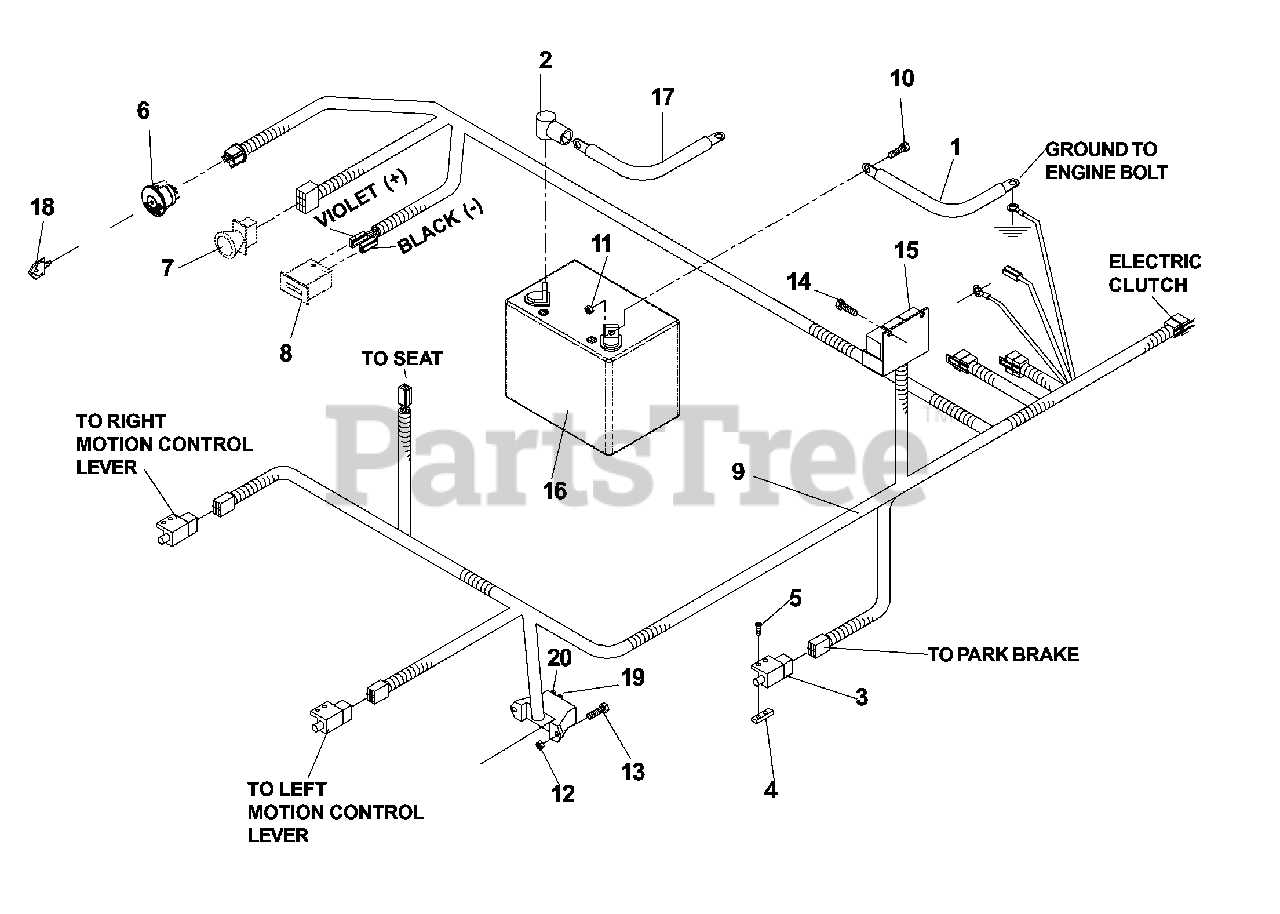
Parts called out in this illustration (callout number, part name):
1	CABLE-NEGATIVE
2	INSULATOR
3	SWITCH, INTERLOCK
4	TAPPED PLATE
5	SCREW #10-24 X 5/8
6	IGNITION SWITCH
7	SWITCH, BLADE
8	HOUR METER
9	HARNESS, KODIAK
10	HCS 5/16C X 3/4
11	NUT 5/16 NYLOC
12	NUT 10-24 NYLOC
13	SCREW, #1--24 X 1/2 SLOTTED
14	SCREW #10 X 1/2 SELF TAPPING
16	BATTERY, 12 V 330 AMP TBR
17	POSITIVE CABLE 25-1/2
18	KEY
19	FUSE, 7.5 AMP 32 VOLT ATO
20	FUSE, 20 AMP 32 VOLT ATO
